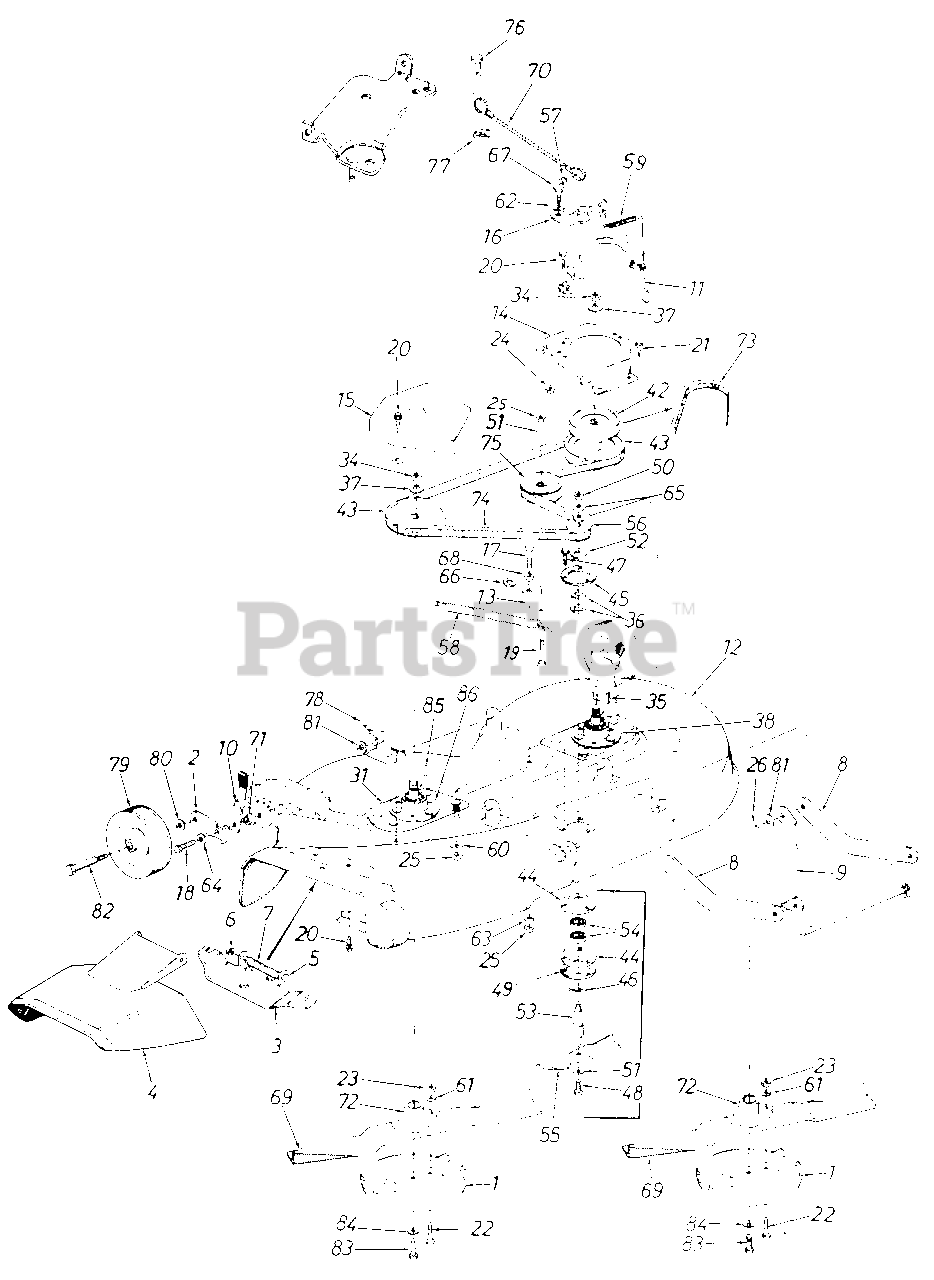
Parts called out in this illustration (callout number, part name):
1	Anti-Scalp Plate
2	Wheel Pivot Bar
3	Adapter
4	Chute Cover Ass'y.
5	Hinge Pin
6	Cap Speed Nut 1/4" Rod.
7	Torsion Spring
11	Belt Guard
12	44" Deck Ass'y.
13	Idler Bracket
14	Pulley Cover-L.H.
17	Hex Bolt 3/8-24 x 1.00"*
18	Hex Bolt 3/8-24 x 1.25"Lg.*
19	Hex Bolt 3/8-24 x 1.50"*
20	Hex Wash. S-Tapp Scr.1/4-20 x .50"*
21	Hex Wash. Hd. Tapp Scr. 5/16-18 x .75" Lg.
22	Hex Bolt 5/16-24 x 1.25"(Grade 5)
23	Hex Nut 5/16-24 Thd.*
24	Hex Cent. L.Nut 5/16-18 Thd.
25	Hex Nut 3/8-24 Thd.*
26	Coter Pin 3/32 Dia. x 1.00" Lg.*
34	Hex Jam Nut 5/8-18 Thd.
35	Square Key 3/16 x 2.25" Lg.
36	Fl. Wash. 5/8" I.D. x 15/16" O.D.
37	Bell. Wash. .630 I.D. x 1.25 x .090
38	L.H. Blade Spindle Ass'y. Comp.
42	5/8 "V" Pulley .79 I.D. x 5.75 O.D.
43	"V" Pulley .79 I.D. x 6.50 O.D.
44	1-3/8" I.D. Bearing Housinc
45	Reinforcement Plate
46	Bearing Shield
47	Hex "B" Tap Scr. .250" x 1.0" Lg.
48	Hex Cl.Scr. 3/8-24 x .88 Lg.
49	Reinforcement Plate
50	Hex Jam Nut 1/2-20 Thd.
51	Bell.Wash. .400 I.D. x .88 O.D. x .060
52	Fl.Wash. .635 x 1.04 O.D. x .1 20"
53	6.5" Blade Spindle
54	Ball Brg. .62 I.D. x 1.30" O.D. x .44"
55	6.50" Blade
56	1/2" V-Pulley Half .625 I.D. x 2.25" O.D.
57	Cap Speed Nut 1/4" Rod.
58	Extension Spring .73 O.D. x 4.31 Lg.
59	Extension Spring
60	Bell.Wash. .400 I.D. x .88 O.D. x .060
61	L.Wash. 5/16" I.D.*
62	Spring Wash. .445 I.D. x .75 O.D. x .017
64	Bell.Wash. .400 I.D. x 1.13 O.D. x .030
65	Bell.Wash. .505 I.D. x 1.00 O.D. x .075
66	Spring Wash. .650 I.D. x .875 O.D. x .015 Thk.
67	Shld. Bolt .437 Dia. x .180
68	Shld. Spacer.625 I.D.
69	Mower Blade 21.88
70	Brake Cable Ass'y.
71	Shld. Spacer
72	Blade Adapter
73	"V"Belt 1/2 x 56" 4.
74	"V"Belt 1/2 x 74" Lg.
75	Fl.ldler w/Flanges 3.50 O.D.
76	Clevis Pin 1/4 Dia. x .53 Lg.
77	Intern. Coter Pin 5/16" Dia.
78	Intern. Coter Pin 1/2" Dia.
79	Deck Wheel 6.0 x 1.38
80	Bell.Wash. .400 I.D. x .88 O.D. x.060
81	Fl.Wash. .531 I.D. x .93 O.D. x .090
82	Shoulder Bolt 3/8-16 x 1.41
83	Hex Bolt 3/8-24 x .88" Lg.
84	L.Washer 3/8 I.D.*
85	Sq. Key 3/16 x .75" Lg.
86	R.H. Blade Spindle Ass'y. Comp.
